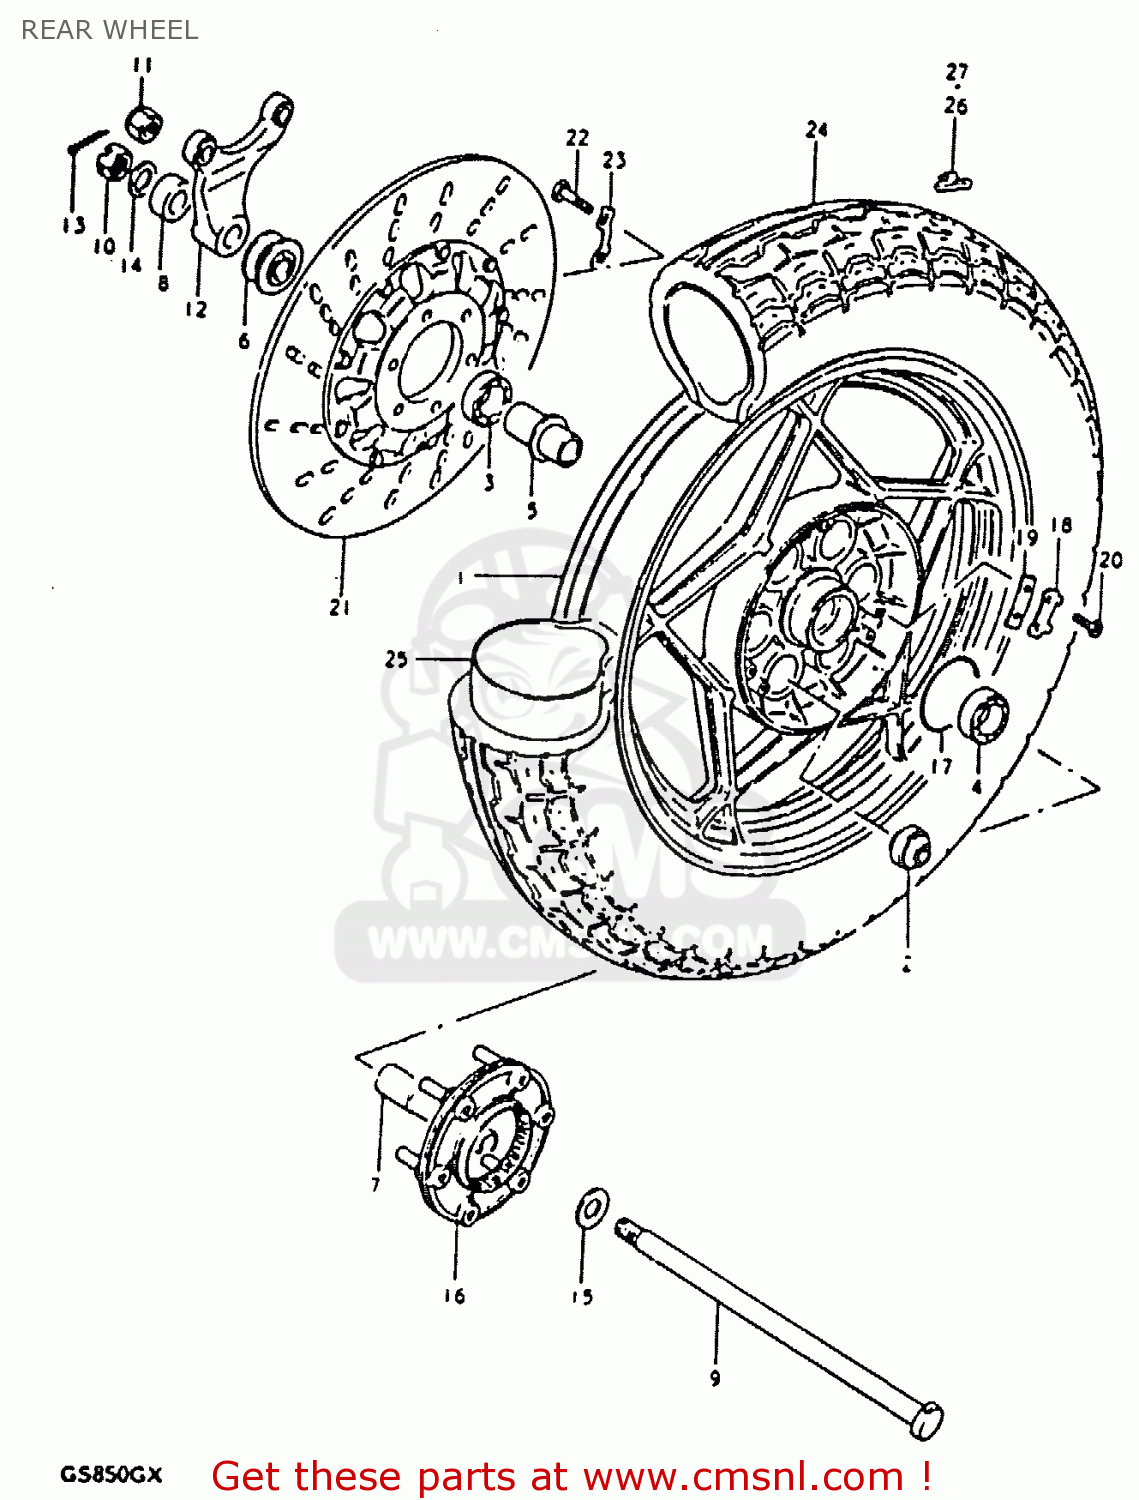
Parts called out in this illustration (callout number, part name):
1	CASTING WHEEL,REAR
2	BUSH
3	BEARING
4	BEARING
5	SPACER,REAR HUB BEARING
6	SPACER,REAR AXLE
7	SPACER,REAR AXLE,LEFT
8	SPACER (17X33X15.2)
9	AXLE,REAR
10	NUT
12	BRACKET,RR,CALIPER
13	PIN,COTTER
14	WASHER
15	WASHER (17.5X36X3.2)
16	JOINT ASSEMBLY,REAR HUB DRUM
17	O RING(D:2.1,ID:65)
18	JOINT WASHER
19	WASHER,THRUST(T:1.6)
20	SCREW
21	DISC,RR BRAKE
22	BOLT(8X30)
23	WASHER
24	TIRE 4.50H17
25	TUBE ASSEMBLY,WHEEL,INNER
26	BALANCER,WHEEL
